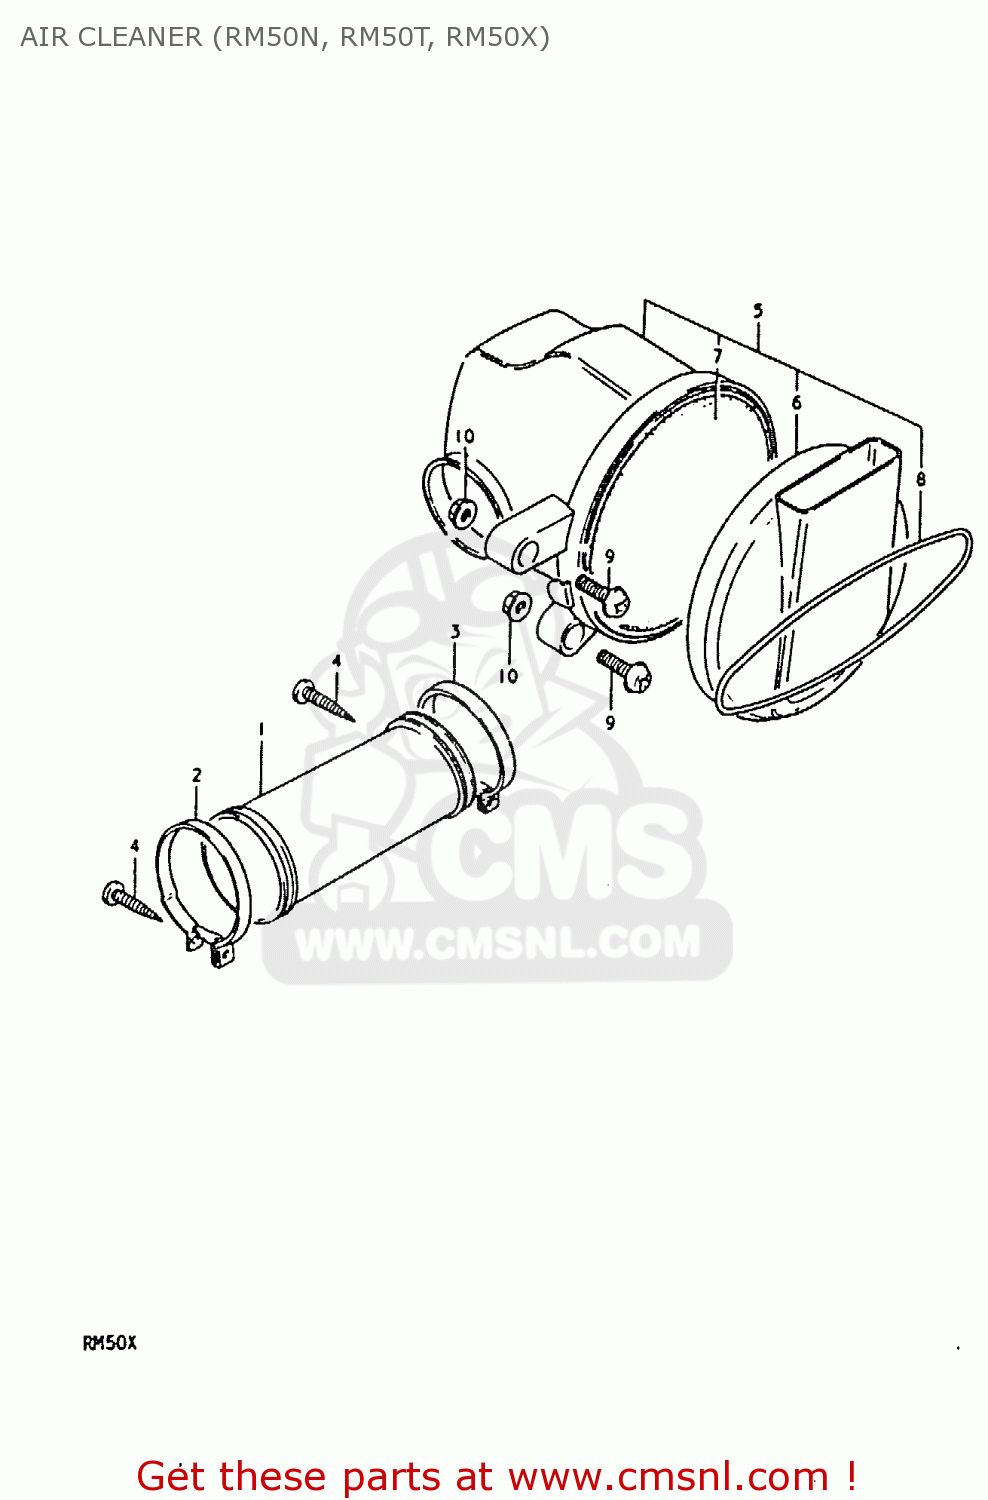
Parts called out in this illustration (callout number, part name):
1	HOSE,CARBURETOR AIR INLET
2	CLAMP
3	CLAMP
4	SCREW TAPP.
5	CLEANER ASSEMBLY,AIR
6	CAP
7	FILTER
8	O-RING,AIR CLEANER
9	SCREW
10	NUT 6MM
